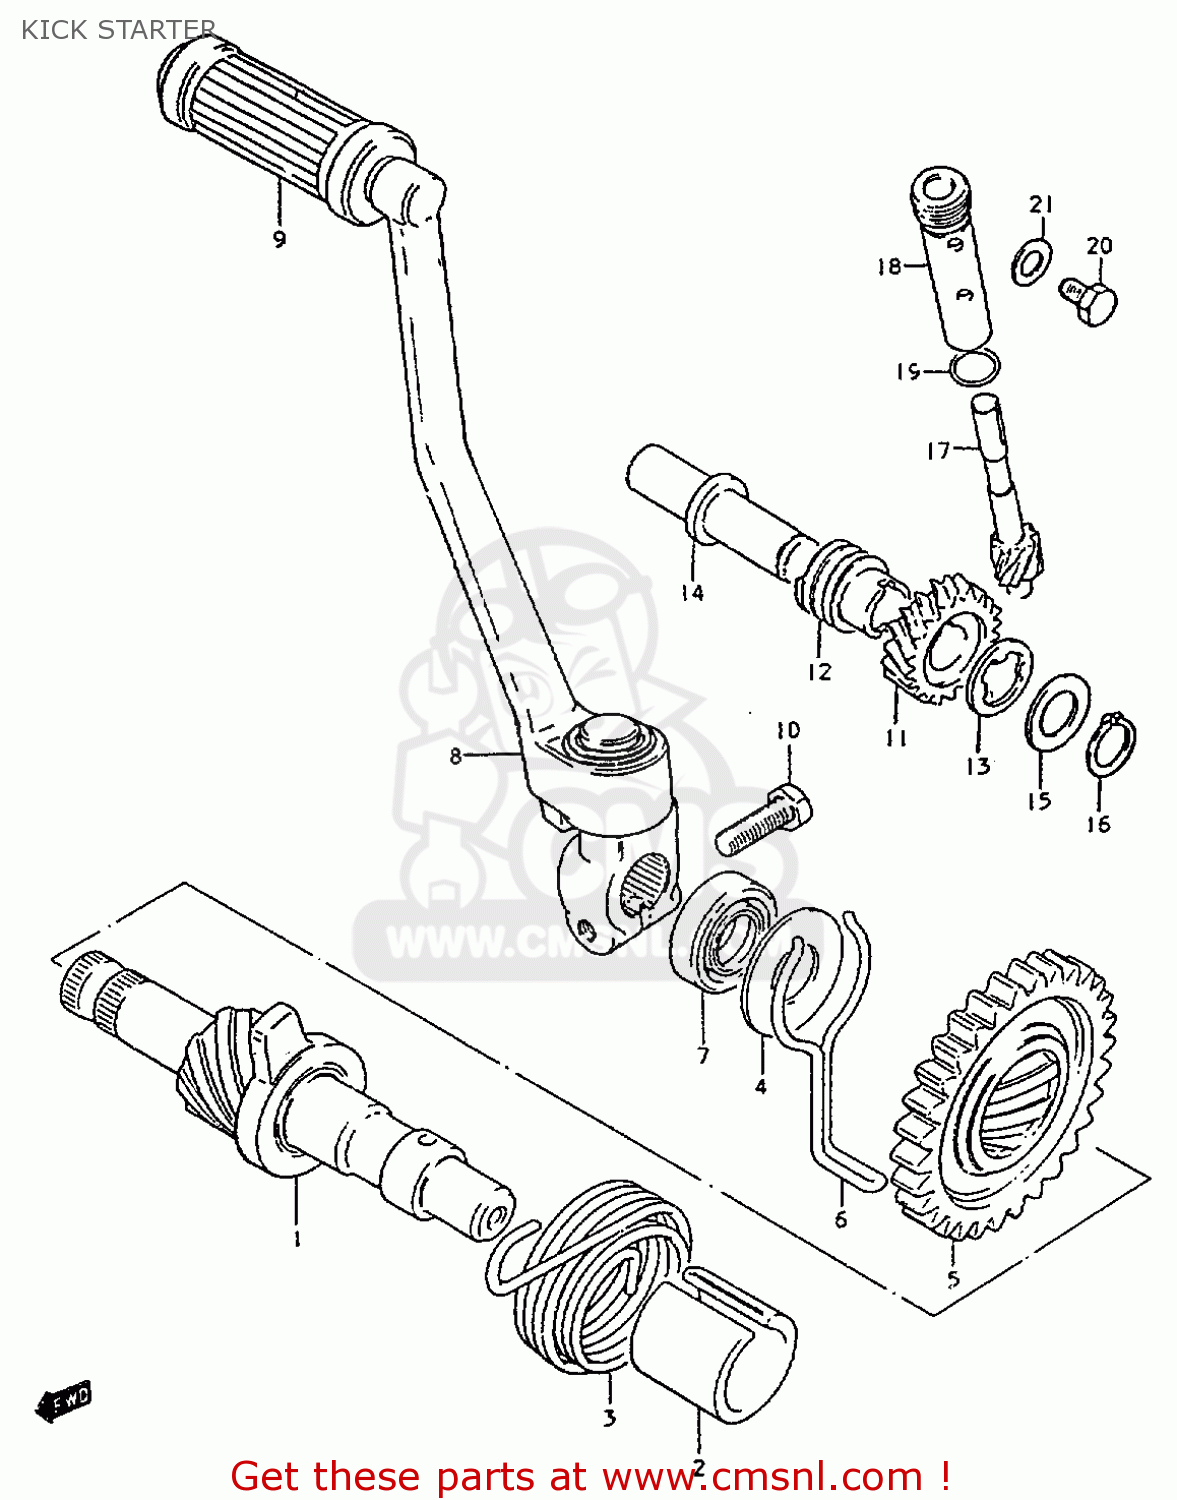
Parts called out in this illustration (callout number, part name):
1	SHAFT,KICK STARTER
2	GUIDE,KICK STARTER SFT SPRING
3	SPRING
4	WASHER
5	GEAR,KICK STARTER DRIVE(NT:30)
6	RETAINER,SNAP
7	SEAL,OIL(14X24X6)
8	LEVER ASSY, KICK STARTER
9	RUBBER,KICK STARTER PEDAL
10	BOLT
11	GEAR, TACHOMETER DRIVE NO.2
12	GEAR,TACH DRIVE NO.2(NT:3)
13	RETAINER,TACH DRIVEN GEAR NO1
14	SHAFT,TACHOMETER DRIVEN GEAR
15	WASHER,THRUST
16	CIRCLIP
17	GEAR,TACHOMETER DRIVEN(NT:12)
18	SLEEVE
19	O RING(D:1.3,ID:9.6)
20	BOLT
21	GASKET(6.2X11X1).2 (NAS)
